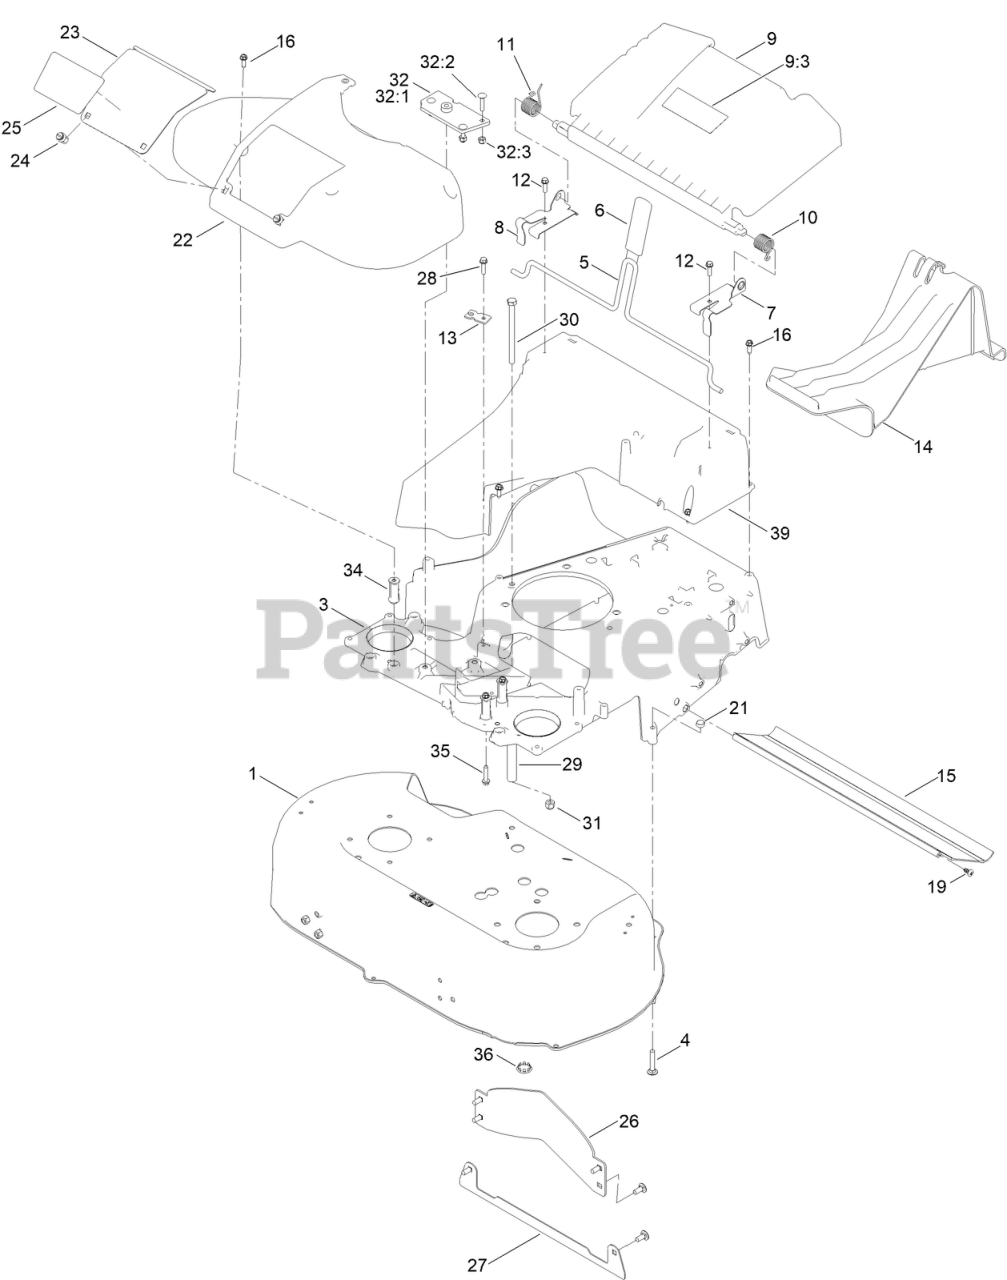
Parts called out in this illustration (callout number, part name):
1	HOUSING ASM
3	FRAME-30"
4	BOLT-CAR
5	ROD-RELEASE, HANDLE
6	GRIP-LEVER
7	BRACKET-DOOR, LH
8	BRACKET-DOOR, RH
9	REAR DEFLECTOR ASM
9:3	DECAL-WARNING
10	SPRING-TORSION
11	SPRING-TORSION
12	SCREW-PLASTITE, HWH
13	BRACKET-CABLE, TRACTION
14	PLUG-MULCH
15	SHIELD-TRAILING
16	SCREW-HWHTF
19	SCREW-THD
21	NUT-HEX
22	COVER-BELT
23	DOOR-ACCESS
24	FASTENER
25	DECAL-ACCESS PANEL
26	BAFFLE-CONTROL
27	PLATE-DECK
28	SCREW-HWHTF
29	SPACER-SHIELD
30	SCREW-HH
31	NUT-HEX
32	FRAME PLATE KIT
32:1	PLATE-FRAME
32:2	SCREW-CARR
32:3	NUT-LOCK, NI
34	SPACER-FRAME, 30 IN.
35	SCREW-HWHTF
36	PLUG-BUTTON
